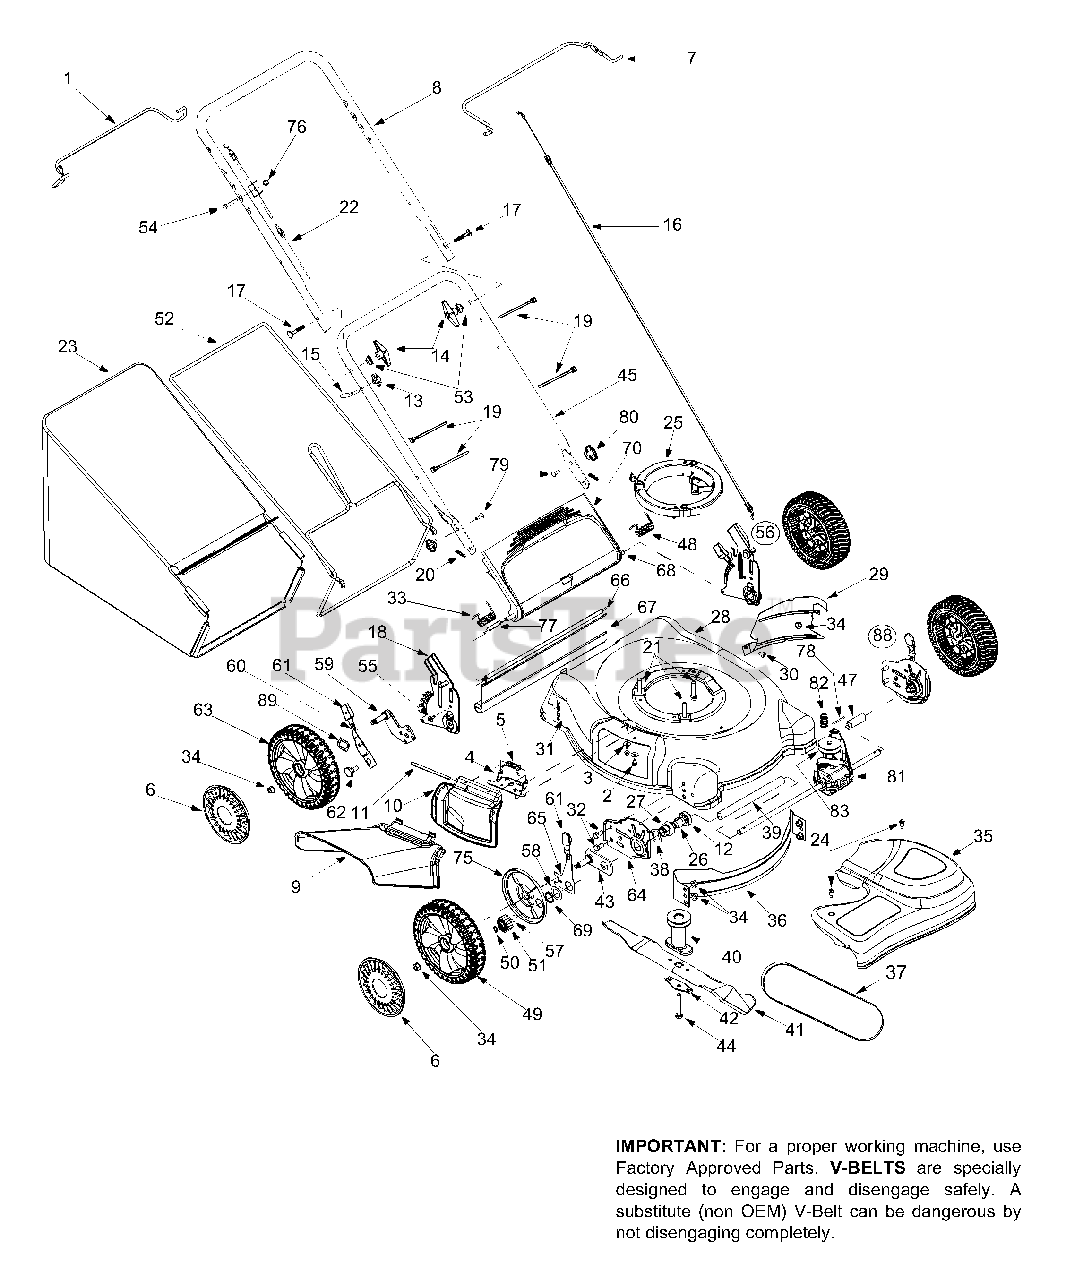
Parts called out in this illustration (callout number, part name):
1	Lower Bail Handle
2	TT Screw 1/4-20 x 0.5
3	Bell Washer.265 x 0.75
4	Deflector Chute Adapter
5	Torsion Spring
6	Hub Cap
9	Chute Deflector
10	Mulch Plug Complete
11	Hinge Pin
12	Bearing Retainer
13	Handle Knob
14	Handle Knob
15	Eye Bolt
16	Control Cable - 40.75"
17	Carriage Bolt 5/16-18 x 2.0
18	RH Handle Bracket
19	Cable Tie
20	Cotter Pin
21	Self-Tapping Sems Screw
22	Drive Cable
23	Grassbag Assembly
24	Shoulder Screw # 12 -24
25	Engine Spacer
26	Bearing Sleeve
27	Bearing Support
28	21" Deck
30	Screw AB: 1/4-14:.625
32	Hex Screw 3/8-16 x.75
33	Torsion Spring RH
34	Flange Lock Nut 3/8-16
35	Transmission Cover (Yellow)
38	Wave Washer
39	Sleeve Spacer 9.04" Lg.
40	Blade Adapter w/ Pulley
41	21" Mulching Blade
42	Blade Bell Support
43	Pivot Plate Assembly
44	Hex Screw 3/8-24 x 2.50
47	Slev. Spacer 2.1" Lg.
48	Torsion Spring LH
49	Front Wheel
50	Snap Ring
51	Gear 14T RH FWD
53	Saddle Washer
54	Hex Screw 1/4-20 x 1.50
55	TT Scr. w/Washer 1/4-20 x.625
56	RH Handle Bracket Assembly
57	Dowel Pin
58	Washer
59	Pivot Arm Assembly - RH
60	Rear Spring Lever
61	Spring Lever Knob
62	Shoulder Scr.500 Dia. x.434
63	Rear Wheel
66	Wire
67	Rear Trailing Shield
68	Pivot Rod
69	Snap Ring
70	Rear Discharge Door
75	Wheel Dust Cap
76	Hex Lock Nut 1/4-20
77	Spacer.375 x.50 x 1.02" Lg.
78	Roll Pin
79	Carriage Bolt 1/4-20
80	Wing Nut
81	Transmission Assembly
82	Belt Tension Spring
83	Input Pulley
88	Height Adjustment Assembly RH
89	Wave Washer
